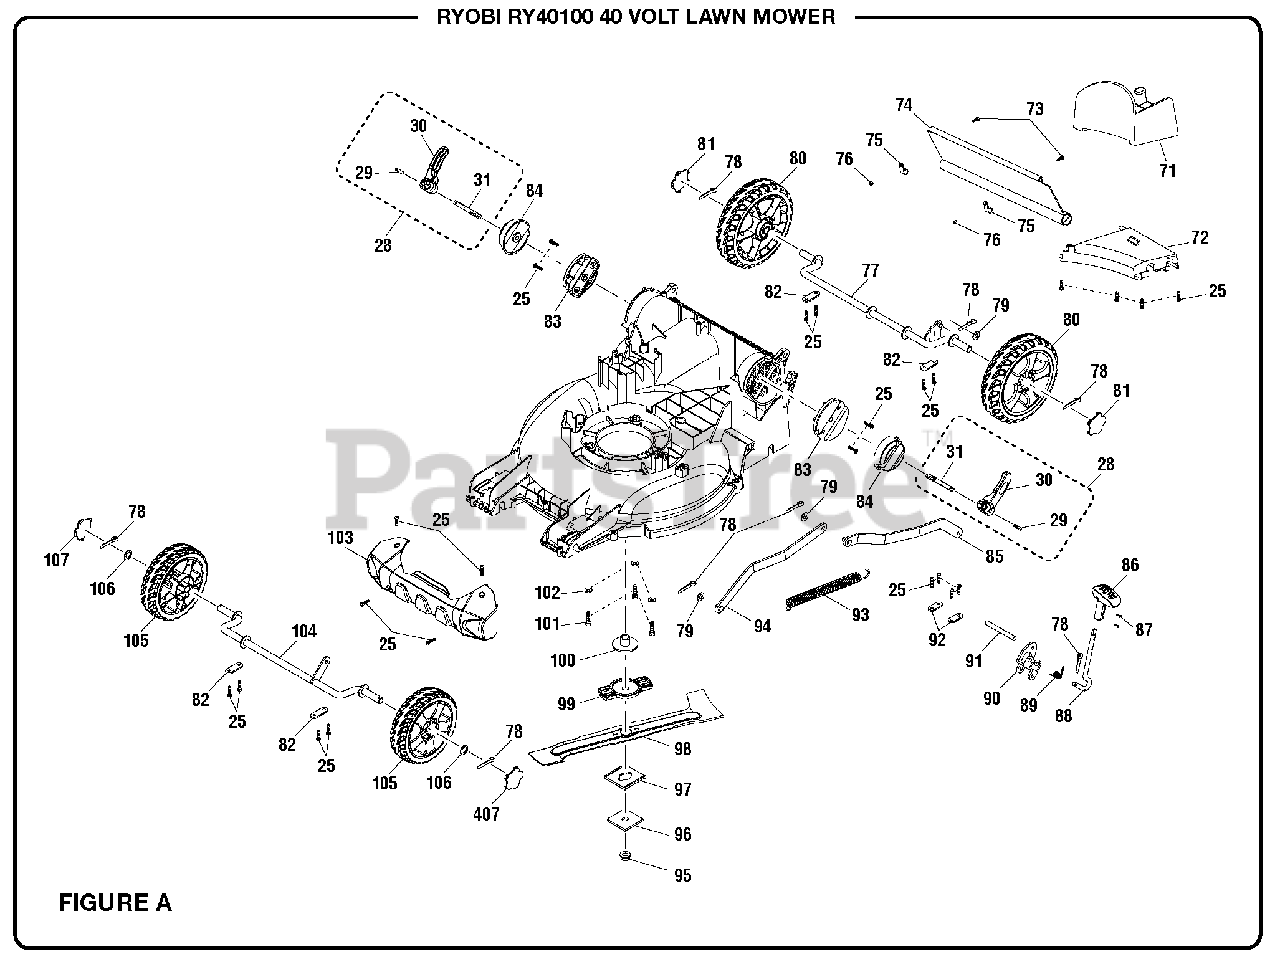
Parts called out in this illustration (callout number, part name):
71	Mulching Plug
72	Rear Cover
73	Screw (M4 x 20 mm, Pan Hd.)
74	Mounting Bracket
75	Lock Nut (M4)
76	Rear Skirt
77	Rear Wheel Axle
78	Cotter Pindia (2.5)
79	Washer (8 mm)
80	Rear Wheel (7 in.)
81	Rear Wheel Cover (7 in.)
82	Axle Pressure Plate
83	Base (Lock Handle)
84	Pressure Block (Lock Handle)
85	Rear Lift Rod
86	Height Adjustment Handle
87	Screw (M3 x 10 mm, Flat Hd.)
88	Height Adjustment Lever
89	Torsion Spring (Height Adjustment)
90	Height Adjustment Bracket
91	Axle (Height Adjustment)
92	Pressure Plate (Height Adjustment)
93	Retention Spring
94	Front Lift Rod
95	Blade Nut (M10 x 1.25, Hex Hd.)
96	Blade Retainer
99	Blade Holder
100	Motor Shaft Bushing
101	Bolt (M6 x 25 mm, Hex Hd.)
102	Washer (6 x 18 x 1.3t)
104	Front Wheel Axle
105	Front Wheel (6 in.)
106	Washer (13.5 x 20 x 1.5t)
107	Front Wheel Cover (6 in.)
